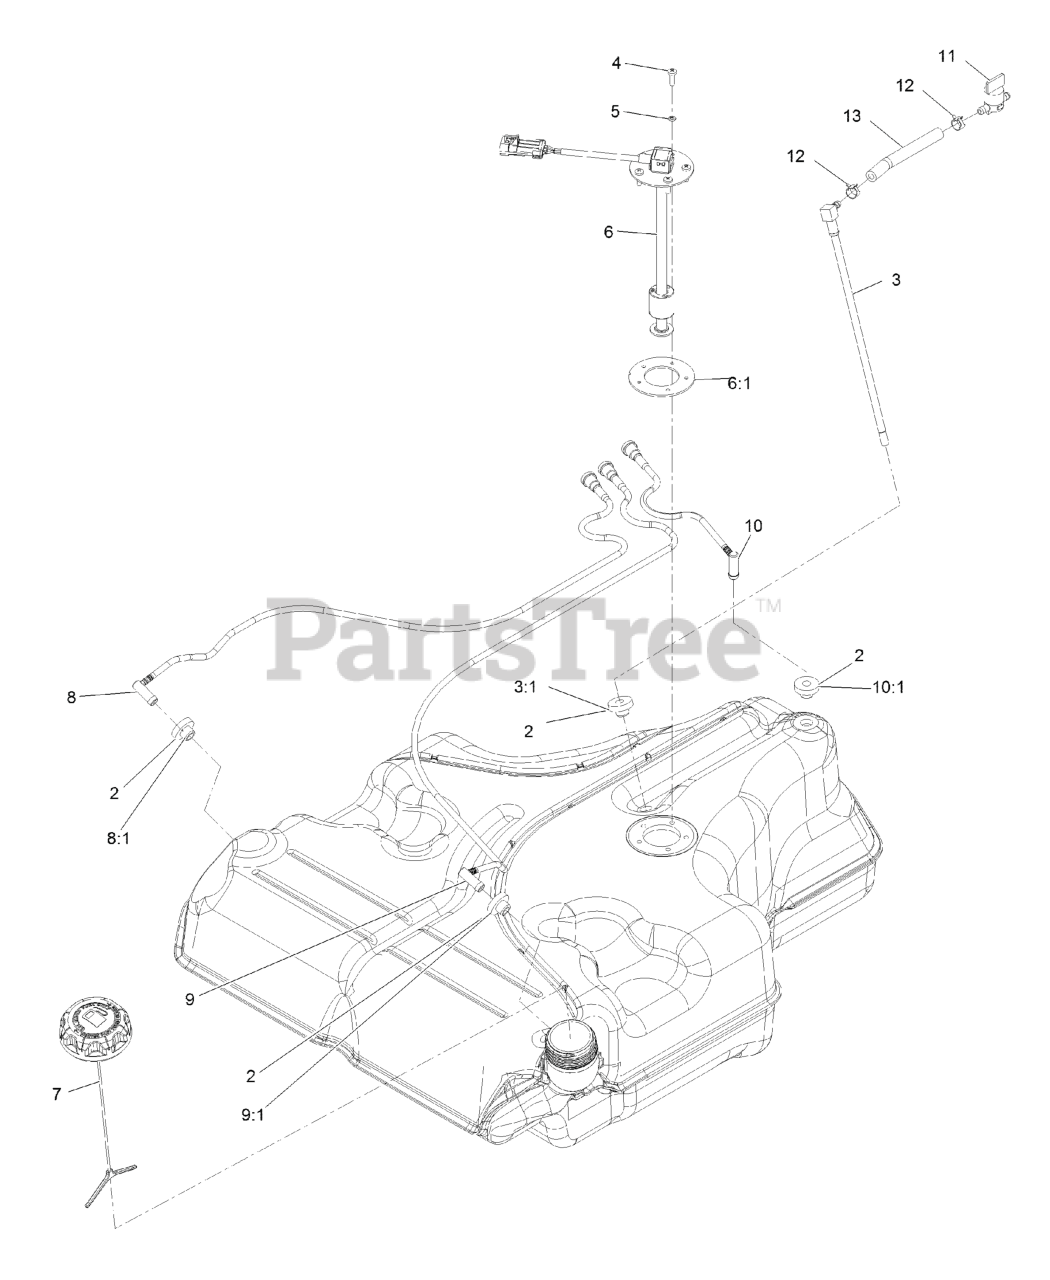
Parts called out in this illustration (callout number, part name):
2	NUT-JAM
4	FUEL MANIFOLD VENT ASM
4:2	HOSE-FUEL
4:3	HOSE-FUEL
5	CLAMP-HOSE
7	CANISTER-CARBON, 1200CC
8	HOSE-VENT, FORMED
9	VALVE-CHECK, VACUUM
10	HOSE-VENT, FORMED
11	MOUNT-CANISTER
12	CLAMP, T-BOLT
13	Screw-HWH 5/16-18 X 3/4 Tf
14	SCREW-CARR
15	NUT-HF, NI
16	PLUG-PORT
17	RETAINER-LINE, VAPOR
19	PLUG-PLASTIC
